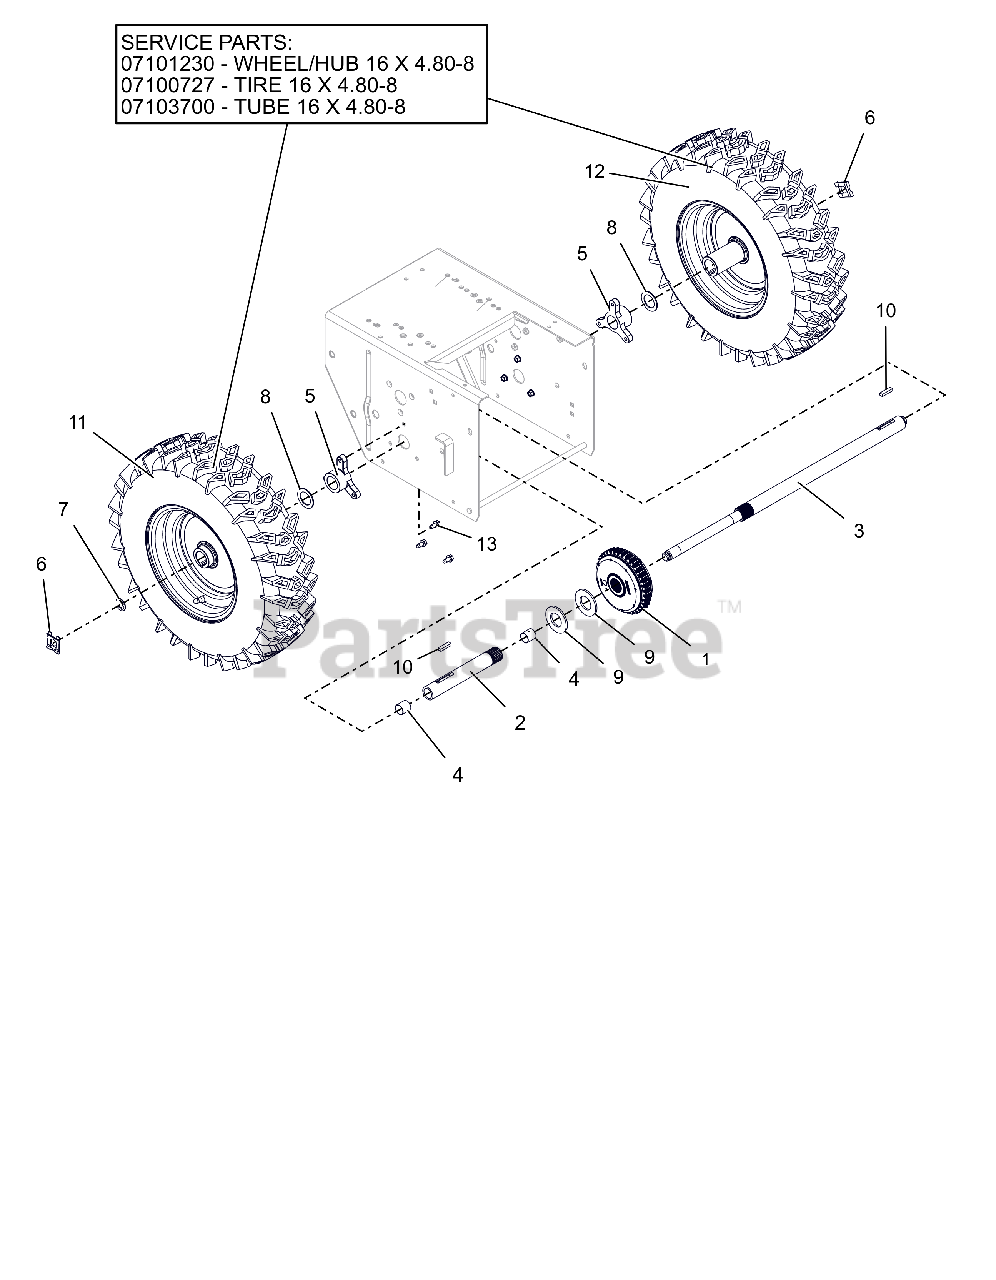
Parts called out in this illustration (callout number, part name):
1	DIFFERENTIAL, AUTOMATIC
2	AXLE, SHORT - W/BUSHINGS
3	AXLE,LONG-DELUXE AUTO DIFF
4	BSHG-SLV .706X.764X.75 BRZ
5	BUSHING, AXLE
6	CLIP, SNAP .625 DIA
7	RG-RTNG-EXT .625X.042
8	WSHR-FL-STL 1.010X1.505X.062YZ
9	WSHR-FL-STL- 1.062X2.0X.134 YZ
10	KEY-RECT .25X.188X1.00
11	TIRE/WHEEL,RH 16X4.8-8 DIFF T2
11	HUB, WHEEL-16X4.8-8
11	TIRE, 4.80-8 K478
11	TUBE
12	TIRE/WHEEL,LH 16X4.8-8 DIFF T2
13	SCR-TAP .25-20X.50 HWH TR YWZ
